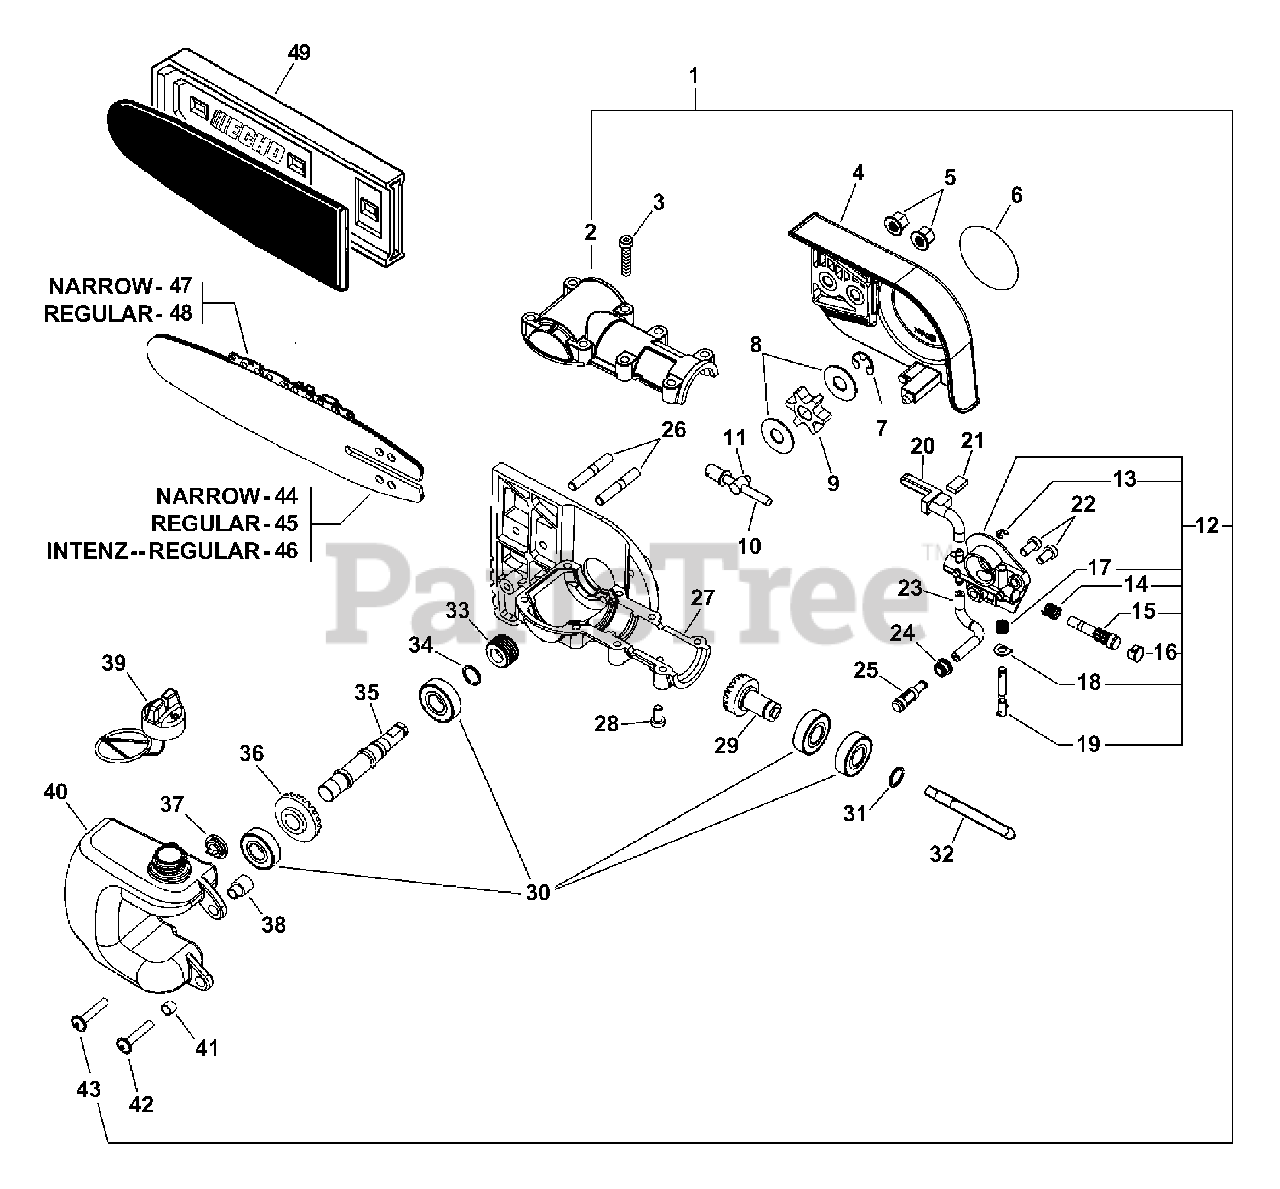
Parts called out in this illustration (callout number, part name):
1	OILER GEAR BOX ASSY
2	CASE, GEAR - UPPER
3	SCREW - 5X25
4	GUARD, SPROCKET
5	NUT - 6 -- FLANGE
6	LABEL - ECHO
7	RING, RETAINING
9	SPROCKET, DRIVE
10	SCREW, TENSIONER
11	TENSIONER, CHAIN
12	AUTO-OILER ASSY
13	RING, RETAINING
14	SPRING, PLUNGER
15	PLUNGER ASSY
16	CAP, OIL PUMP
19	NEEDLE, ADJUST
20	PIPE, OIL OUTLET
21	PAD, FOAM
22	SCREW - 5X10
23	PIPE - 3X6X75 -- BLACK
24	GROMMET
25	FILTER, OIL
26	STUD - 6
27	CASE, GEAR - LOWER
28	SCREW - 5X10
29	GEAR - BEVEL
30	BEARING, BALL - 6001
31	RING, RETAINING - 12
32	CONNECTOR, SHAFT
33	GEAR - WORM
34	RING, RETAINING - 12
35	GEAR - SHAFT
36	GEAR - BEVEL
39	CAP ASSY
40	TANK, OIL
42	SCREW - 5X16
43	SCREW - 5X20
44	GUIDE BAR - 12" (30cm)
45	GUIDE BAR - 12" (30cm)
46	GUIDE BAR - 12" (30cm) Intenz
47	SAW CHAIN - 12" (30cm)
48	SAW CHAIN - 12" (30cm)
49	COVER, GUIDE BAR - 12" (30cm)
